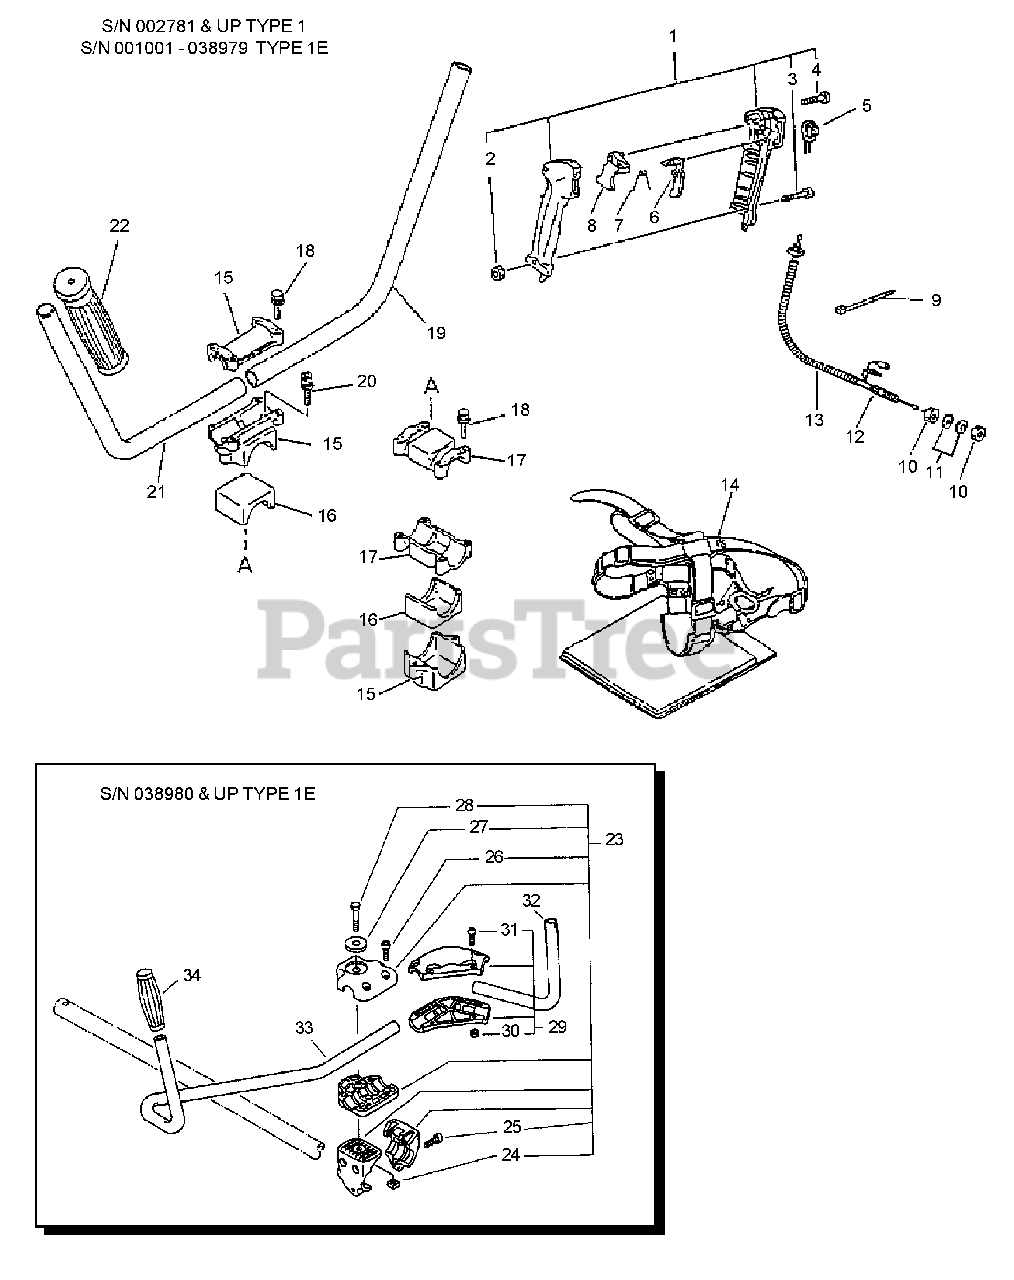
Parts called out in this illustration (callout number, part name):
1	CONTROL HANDLE KIT
2	NUT M5
3	SCREW 5×30
4	SCREW 3×25
5	SWITCH, ON-OFF
6	LOCKOUT, THROTTLE
7	SPRING, TORSION
8	TRIGGER, THROTTLE
9	STRAP, TIE
11	WASHER 6.5×11.5×0.8
12	CABLE, THROTTLE
13	TUBE, FLEXIBLE 7×820
14	HARNESS, SHOULDER
15	BRACKET ASSY, HANDLE
16	CUSHION
17	BRACKET ASSY
18	BOLT - 5×25
19	HANDLE, FRONT
20	BOLT 5×25
21	HANDLE, LEFT
22	GRIP, HANDLE
23	HANDLE BRACKET KIT
24	NUT 8×1.25
25	BOLT 5×30
26	BOLT 5×20
27	WASHER 8
28	BOLT 8×55
29	BRACKET ASSY, HANDLE
30	NUT M5
31	BOLT 5×20
32	HANDLEBAR, RIGHT
33	HANDLEBAR, LEFT
34	GRIP, HANDLE
